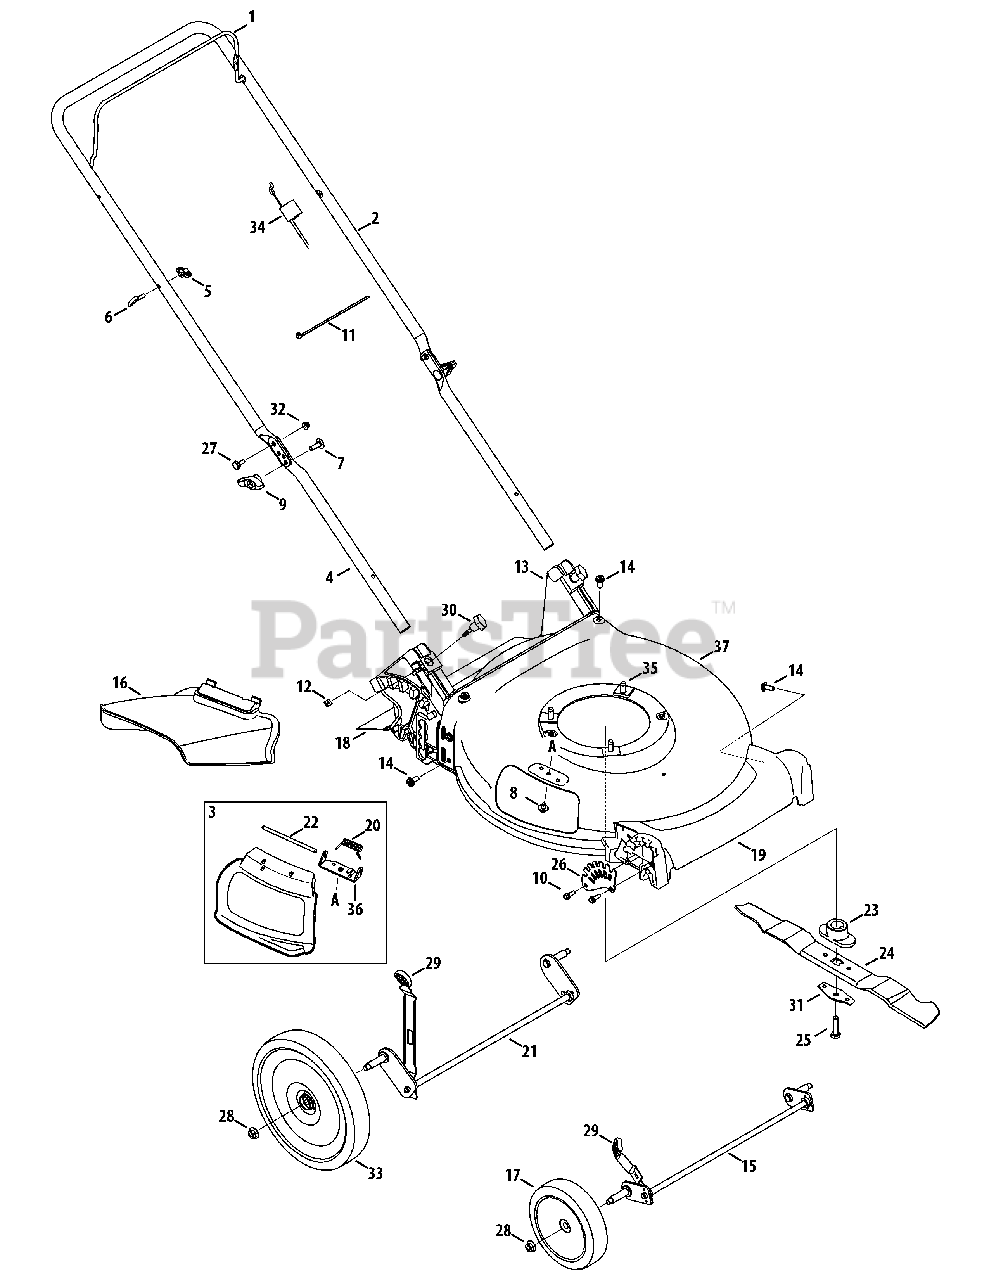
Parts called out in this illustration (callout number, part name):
1	Blade Control
2	Upper Handle, Adjustable
3	Hinged Mulch Plug Assembly
4	Lower Handle
5	Wing Nut
6	Rope Guide
7	Carriage Screw, 5/16-18
8	Screw, 1/4-20 x .500
9	Wing Knob
10	Screw, 1/4-15 x .750
11	Cable Tie
12	Nut, Sq., 1/4-20
13	Rear Baffle
14	Screw, 5/16-14 x .750
15	Front Axle Assembly
16	Side Chute
17	Front Wheel, 7 x 1.8, Gray
18	Trail Shield
19	Front Cover
20	Torsion Spring
21	Rear Axle Assembly
22	Hinge Pin
23	Blade Adapter, 25mm x 1.19
24	Mulching Blade
25	Screw , 3/8-24 x 1.50
26	Front Height Adjuster Plate
27	Sldr. Screw, .375 x .126 x 1/4-20
28	Flange Lock Nut, 3/8-16
29	Adjustment Lever Knob
30	Wing Nut
31	Blade Bell Support
32	Nut, Flange Lock, 1/4-20
33	Rear Wheel, 11 x 1.8, Gray
34	Control Cable, 48.00"
35	TT Sems Screw, 3/8-16 x 1.0
36	Chute Deflector Bracket
37	Deck - 21" - Green
